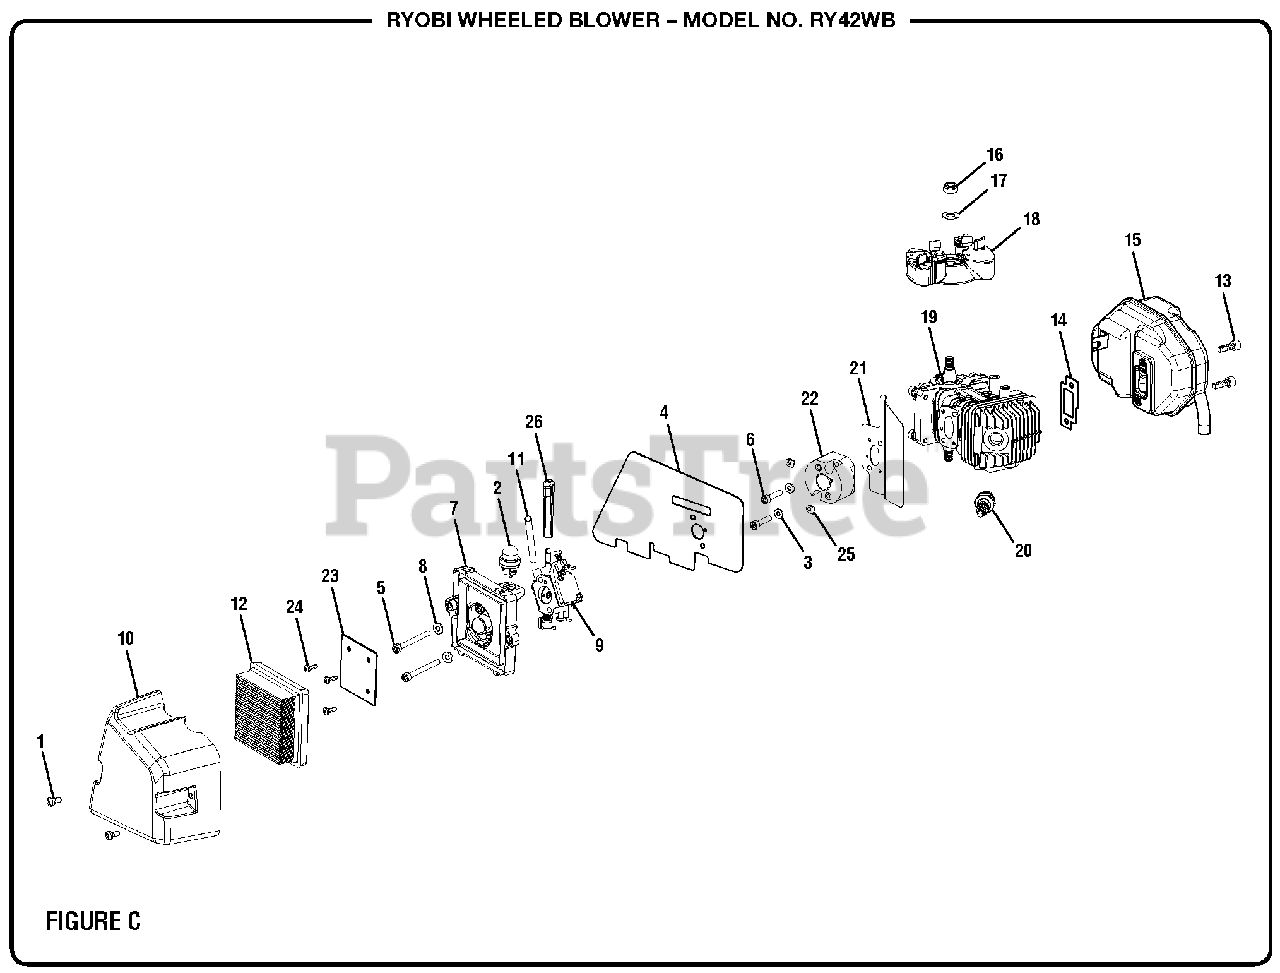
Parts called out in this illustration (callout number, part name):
1	Screw
2	Primer Assembly
3	Spring Washer (M5)
5	Screw (M5 x 50 mm, Soc. Hd.)
6	Screw (M5 x 0.8 in.)
7	Air Box Base
8	Washer (ID5.8 x OD11.5 x 1.7t)
9	Carburetor
10	Air Box Cover
11	Fuel Line
12	Air Filter
13	Bolt (1/4-20 x 18 mm)
15	Exhaust Assembly
16	Lock Nut (M8)
17	Washer (ID9 x OD17.7 x 1.1t)
18	Flywheel Assembly
19	Short Block Assembly
20	Spark Plug (RCJ4)
22	Heat Dam
24	Screw (M4 x 12 mm, Pan Hd.)
25	Washer (Heat Dam)
26	Choke Lever
